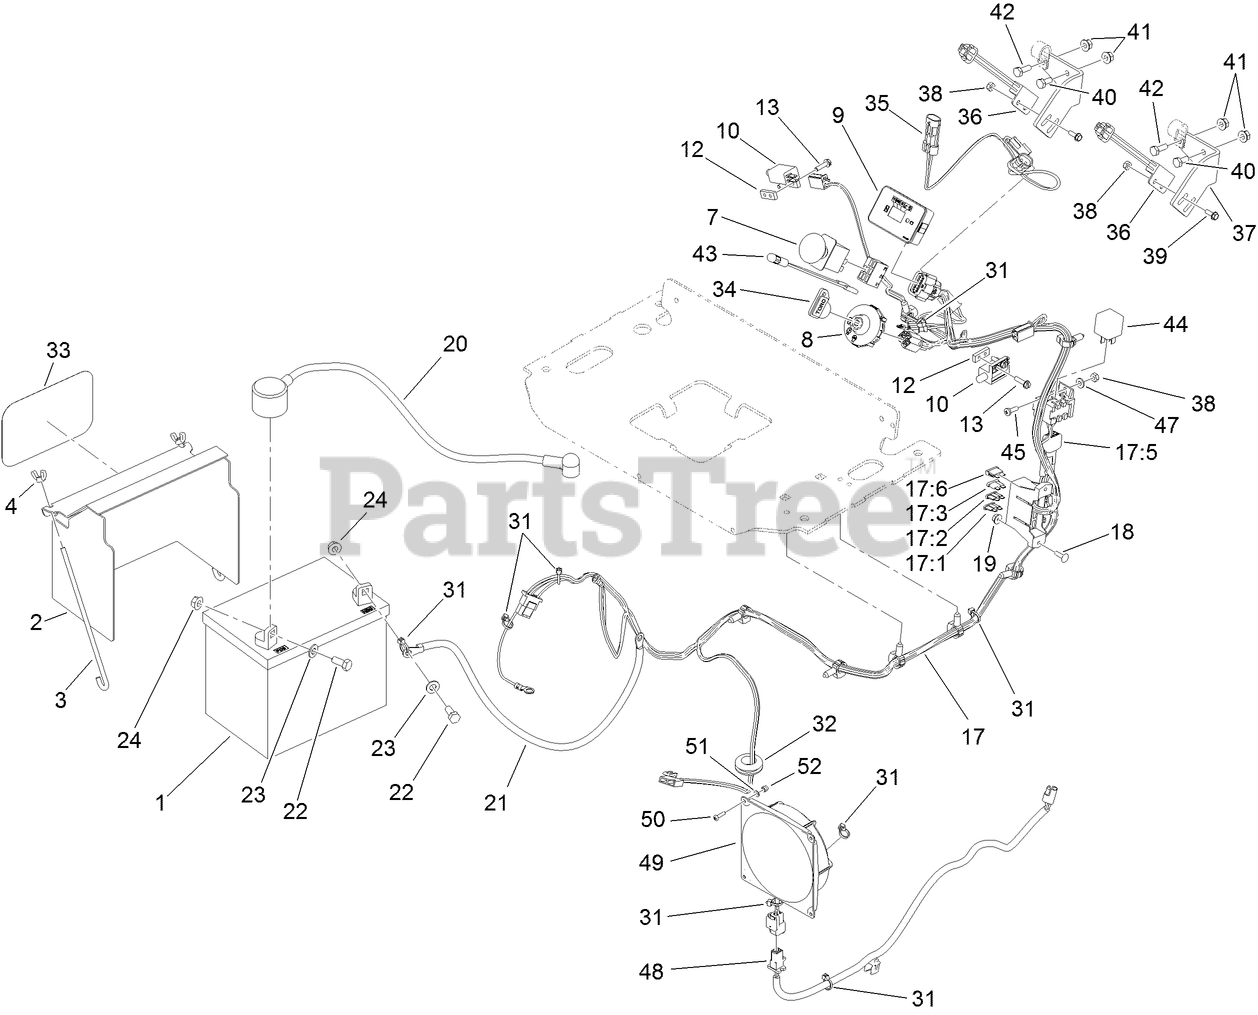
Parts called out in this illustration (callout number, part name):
1	BATTERY-DRY
2	COVER-BATTERY
3	BOLT-HOLDDOWN
4	WINGNUT
7	SWITCH-PTO, ON-ON-(ON)
8	SWITCH-IGNITION
9	MODULE-HOUR METER
10	SWITCH-CLOSED, NORMALLY
12	PLATE-TAPPED
13	SCREW-HWH
17	Harness-Wire, EFI
17:1	FUSE-BLADE, 30 AMP
17:2	FUSE-BLADE, 25 AMP
17:3	FUSE-BLADE, 10 AMP
17:6	FUSE-BLADE, 15 AMP
18	BOLT-CARR
19	NUT-HF
20	CABLE-BATTERY, POSITIVE
21	CABLE-BATTERY, BLACK
22	SCREW-HH
23	WASHER-PLAIN
24	NUT-HHF, SMOOTH
31	TIE-CABLE
32	GROMMET
33	DECAL
34	KEY-IGNITION
35	HARNESS-WIRE, NEUTRAL SWITCH
36	SWITCH-PROXIMITY
37	BRACKET-MOUNT, SWITCH
38	NUT-LOCK, NI
40	SCREW-HH
41	NUT-HHF
42	SCREW-HH
43	INDICATOR-LED, RED
45	SCREW-PPH
47	WASHER-FLAT
48	HARNESS-WIRE, FAN
49	FAN-ELECTRIC
50	SCREW-PPH
51	WASHER-FLAT
52	NUT-LOCK
